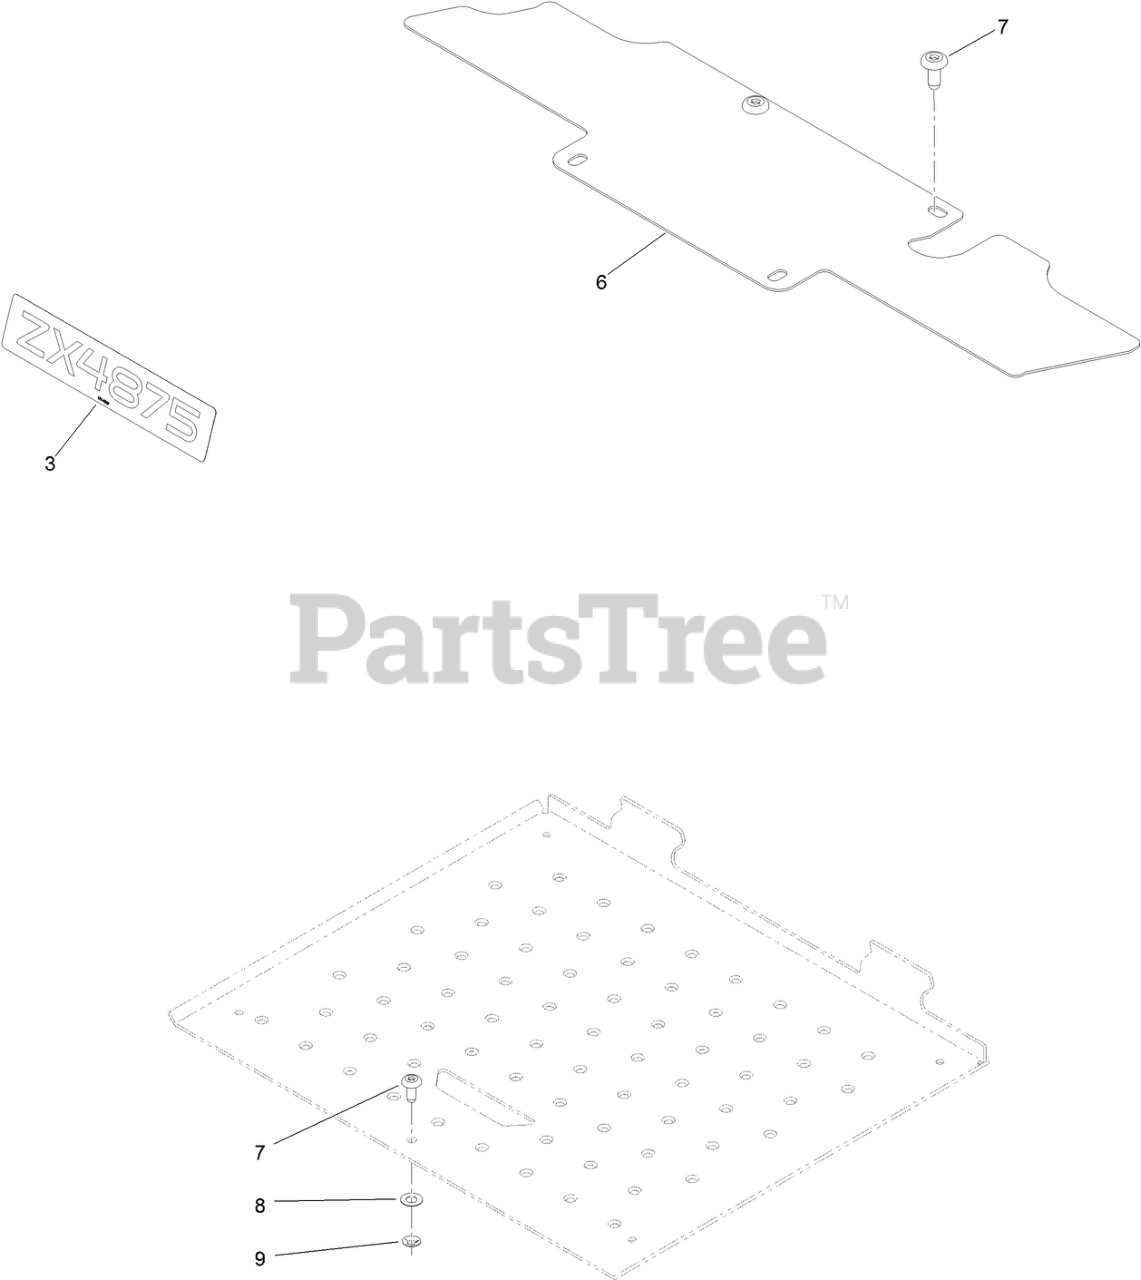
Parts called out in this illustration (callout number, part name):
3	DECAL ZX4875
6	GUARD-BELT
8	WASHER-THRUST
9	NUT-PUSH
